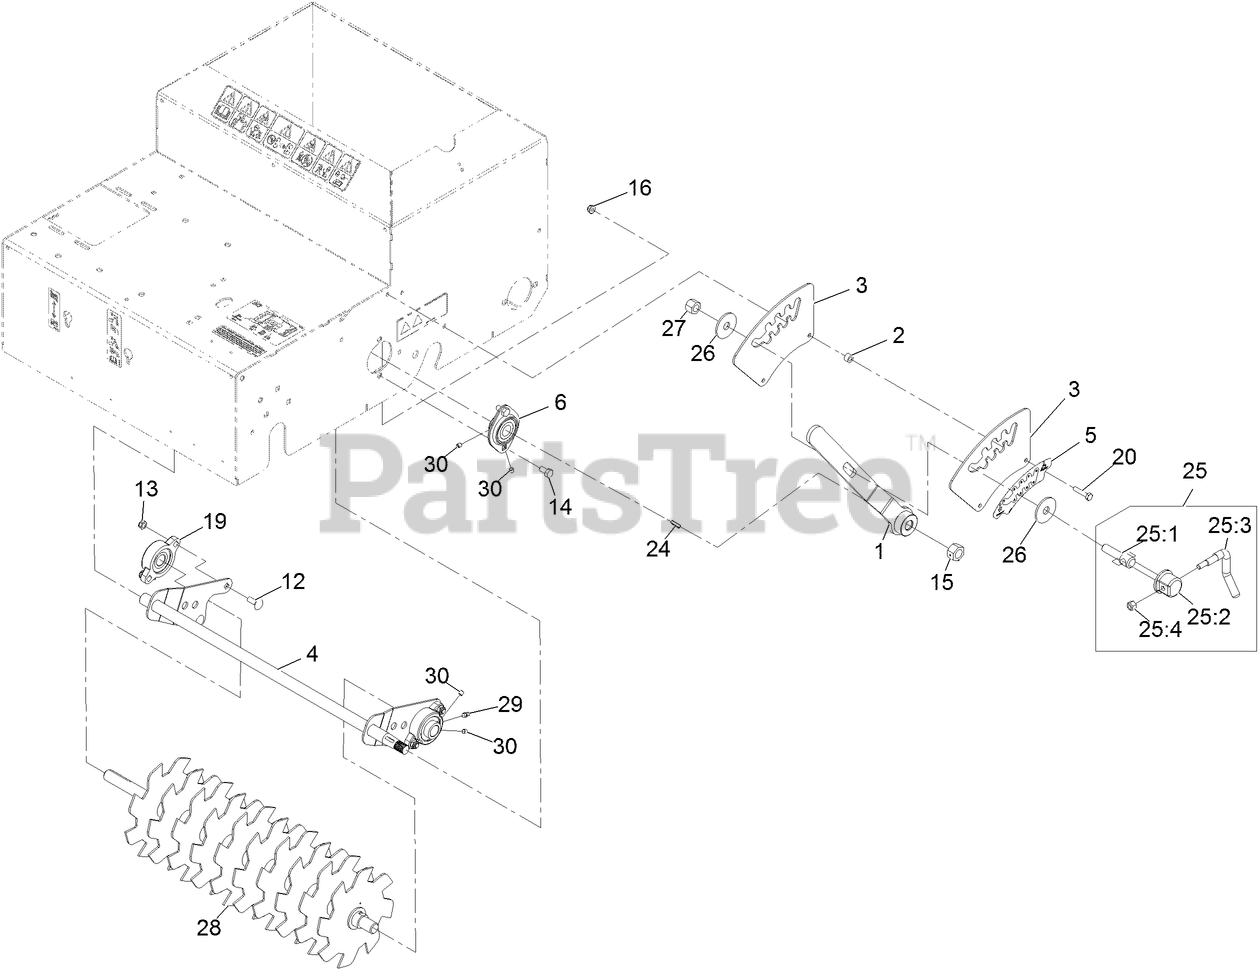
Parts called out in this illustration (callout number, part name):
1	HANDLE-HEIGHT
2	Spacer
3	PLATE-HEIGHT
4	PIVOT-HEIGHT
5	DECAL-CUT DEPTH, SLICER/SEEDER
6	BEARING
12	Bolt-Carriage 5/16-18 x 7/8
13	Nut-Nyloc 5/16-18 Thin
14	Screw-HH 5/16-18 x 5/8
15	NUT-BLADE
16	Nut-Nyloc 1/4-20 Flg
19	BEARING-FLANGE
20	Screw-HH 1/4-20 x 1 1/4
24	Key-Woodruff #9 3/4 x 3/16
25	LEVER ASM
25:1	Screw-Lock
25:2	CAP-LOCK
25:3	Lever-Lock
25:4	Nut-Nyloc 5/16-18
26	Washer
27	Nut-Nyloc 1/2-13
28	SLICER SHAFT ASM
29	Zerk-1/4-28 Str
30	Screw-Set HSH 1/4-28 X 1/4
